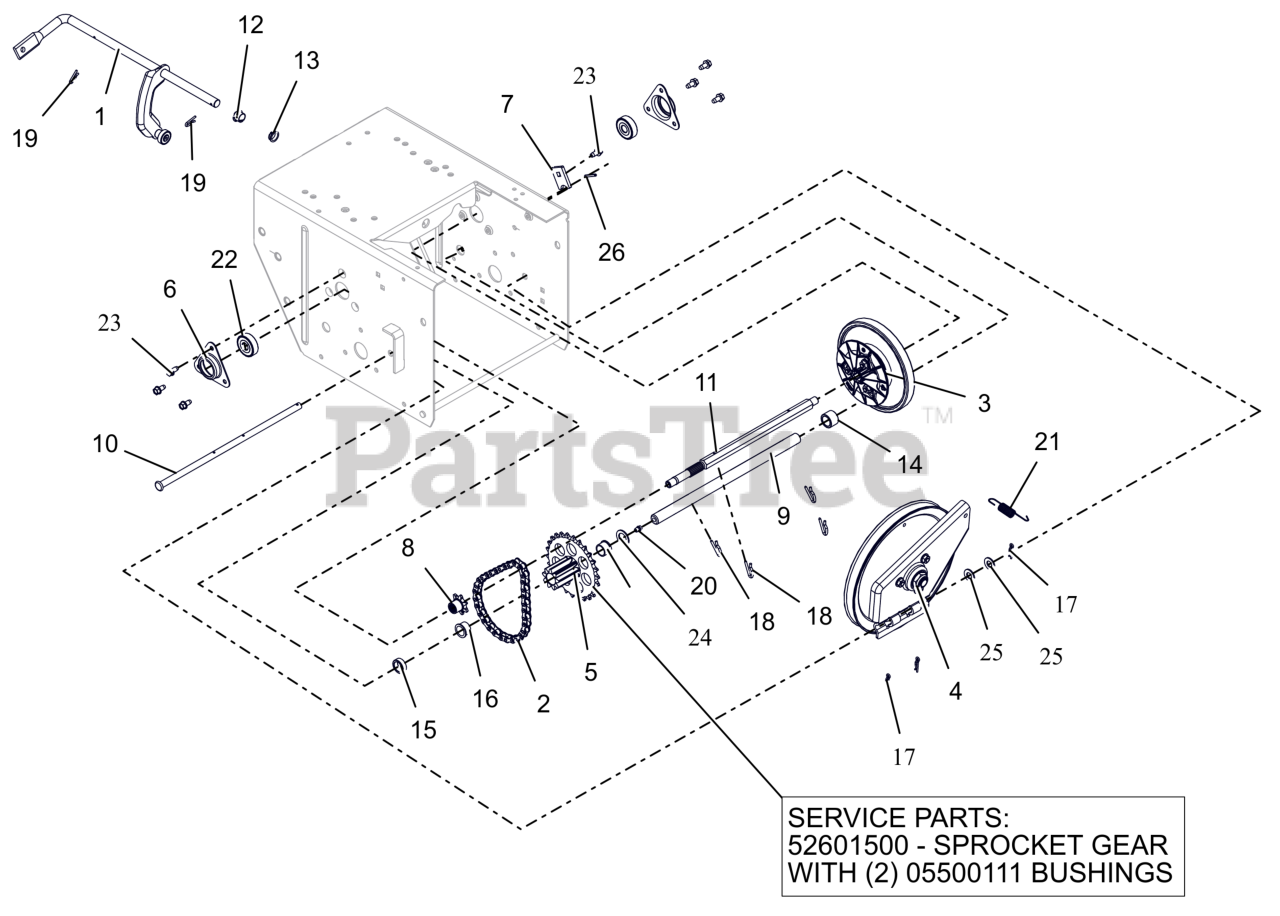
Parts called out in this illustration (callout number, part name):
1	ARM, SHIFT-PRO (ASSEMBLY)
2	CHAIN - #41, 32 PITCHES
3	DISC, FRICTION DRIVE-ASSEMBLY
4	PLATE, SWING ASSEMBLY-DEEP
5	PINION & SPROCKET
5	PINION & SPROCKET W/BUSHINGS
6	FLANGE, BEARING
7	TAB, ANTI ROTATION
8	SPROCKET, PINION 7T W/SPLINE
9	SHAFT, PINION - HARDENED
10	PIN, PIVOT
11	SHAFT, HEX - HEAT TREATED
12	BUSHING, POLYLINER-.50 SPLIT
13	BUSHING, POLYLINER-.50 SNAPIN
14	SPACER, .635X.880X.611
15	BSHG-SLV, .635X.880X.305
16	BSHG-FLG .625X.750X.500X.875
17	PIN, HAIR #225 .072X1.09
18	PIN, SPRING CLIP
19	CLIP, SPRING
20	ZERK,FITTING .25X.125 DRIVE IN
21	SG-TENS .048X.50X2.8
22	BRG-BALL .437X1.375X.437
23	SCR-TAP .25-20X.50 HWH ZCC
24	WSHR, FLT .630X1.005X.062 ZCC
25	WSHR,FLT .406X.812X.065 ZCC
26	PIN-ROLL .125X1.00
